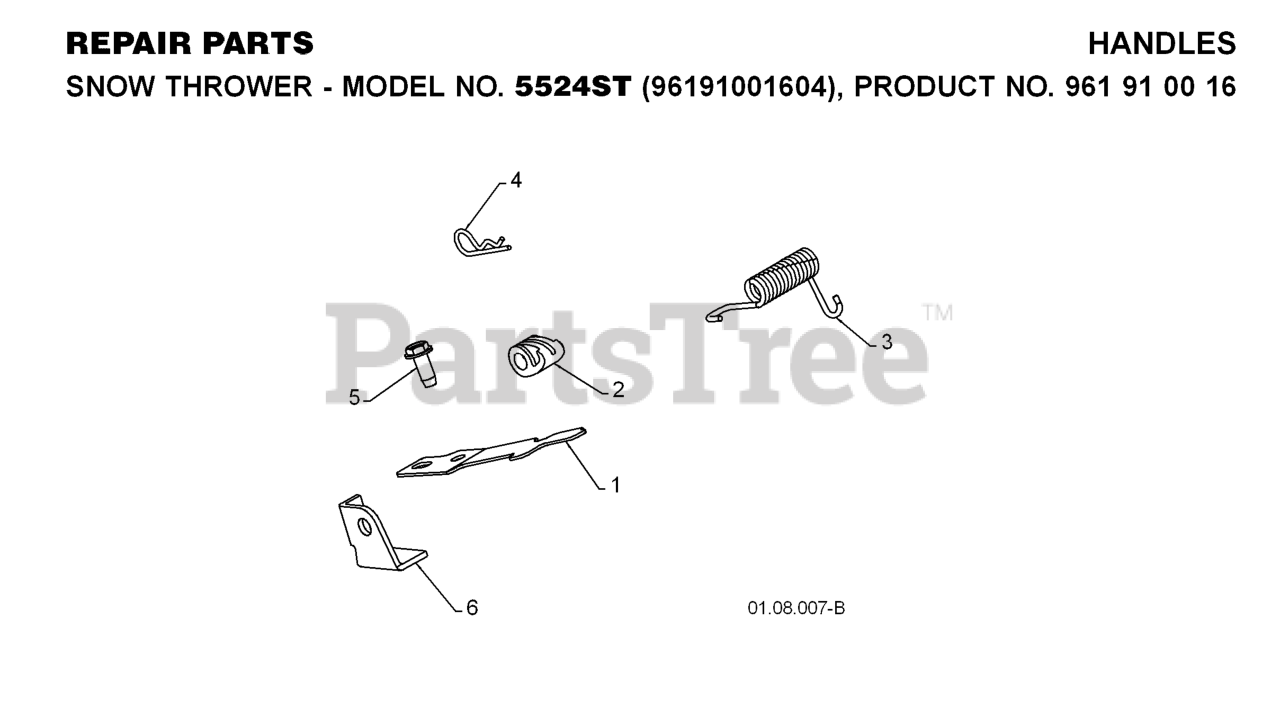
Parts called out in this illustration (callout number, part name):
1	SPRING.INTERLOCK
2	CAM.INTERLOCK.RELEASE
3	RP SPRING, TORSION
4	SPRING RETAINER
5	SCREW 14-20 X 5/8
6	STOP.INTERTLOCK.SPRING
